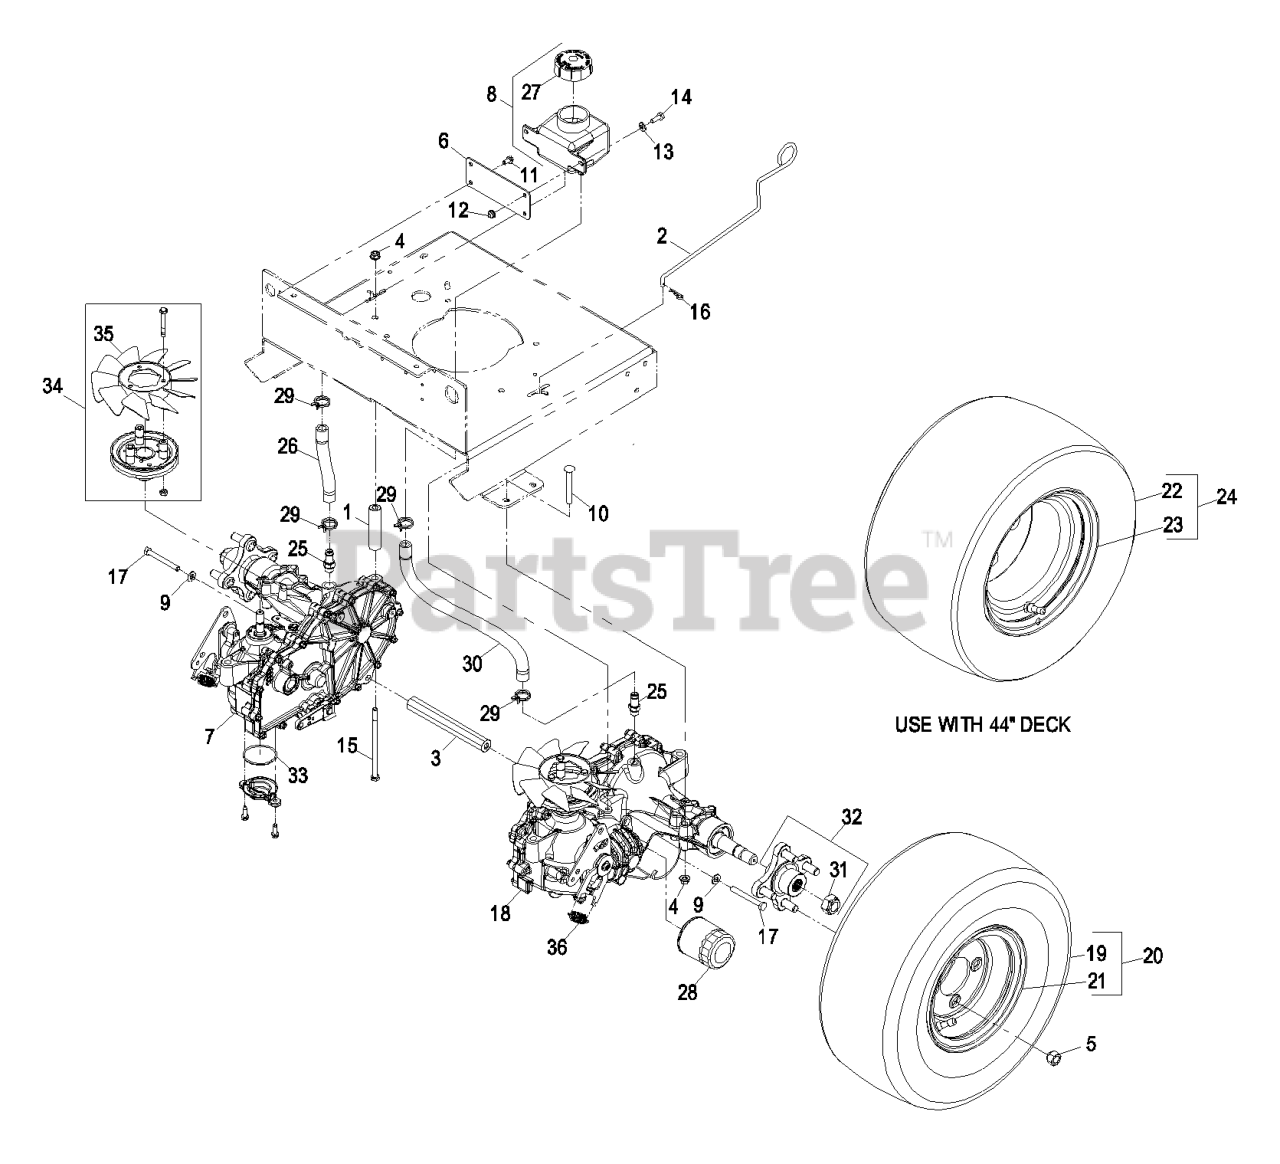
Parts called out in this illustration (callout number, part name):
1	SPACER-HYDRO
2	ROD-BYPASS, HYDRO
3	SPACER-AXLE
4	NUT-HF, NI
5	NUT-LUG
6	PLATE-MOUNT, TANK
8	TANK-HYD
9	WASHER-BELLEVILLE
10	SCREW-CARR
11	SCREW-HWH
13	WASHER-FLAT
14	SCREW-HH
15	BOLT-HH
16	PIN-COTTER
17	SCREW-HH
19	TIRE,18X7X8
20	ASM,TIRE&WHEEL
21	RIM,8X5.38
24	ASM,TIRE&WHEEL
25	ADAPTER-STRAIGHT
26	HOSE-HYD
27	CAP-RESERVOIR, HYD
28	ELEMENT-OIL FILTER, HYD
29	CLAMP-HOSE
30	HOSE-HYD
31	NUT-HUB
33	O RING-SEAL
